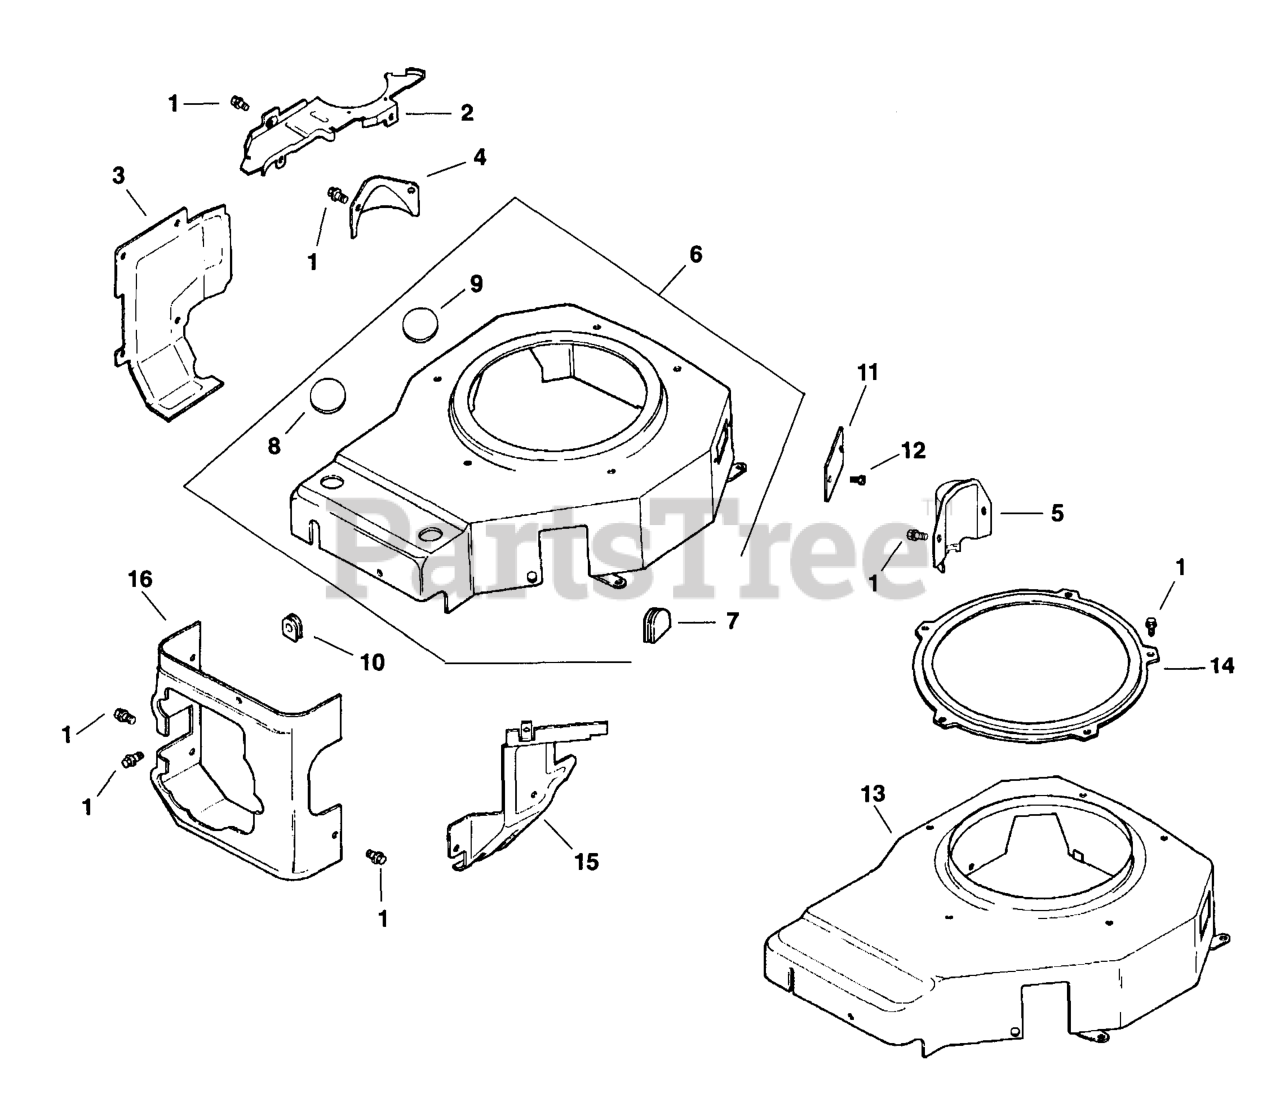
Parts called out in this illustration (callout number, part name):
1	Screw, Hex. Flange M5x0.8x10
2	Plate, Blower Housing Back
3	Baffle, Cylinder Barrel
4	Cover, Starter
10	Grommet, Blower Housing
11	Cover, Rectifier-Regulator
12	Screw, Hex. Flange M6x1.0x16
13	Housing, Blower
15	Baffle, Intake Side
16	Baffle, Cylinder Head
